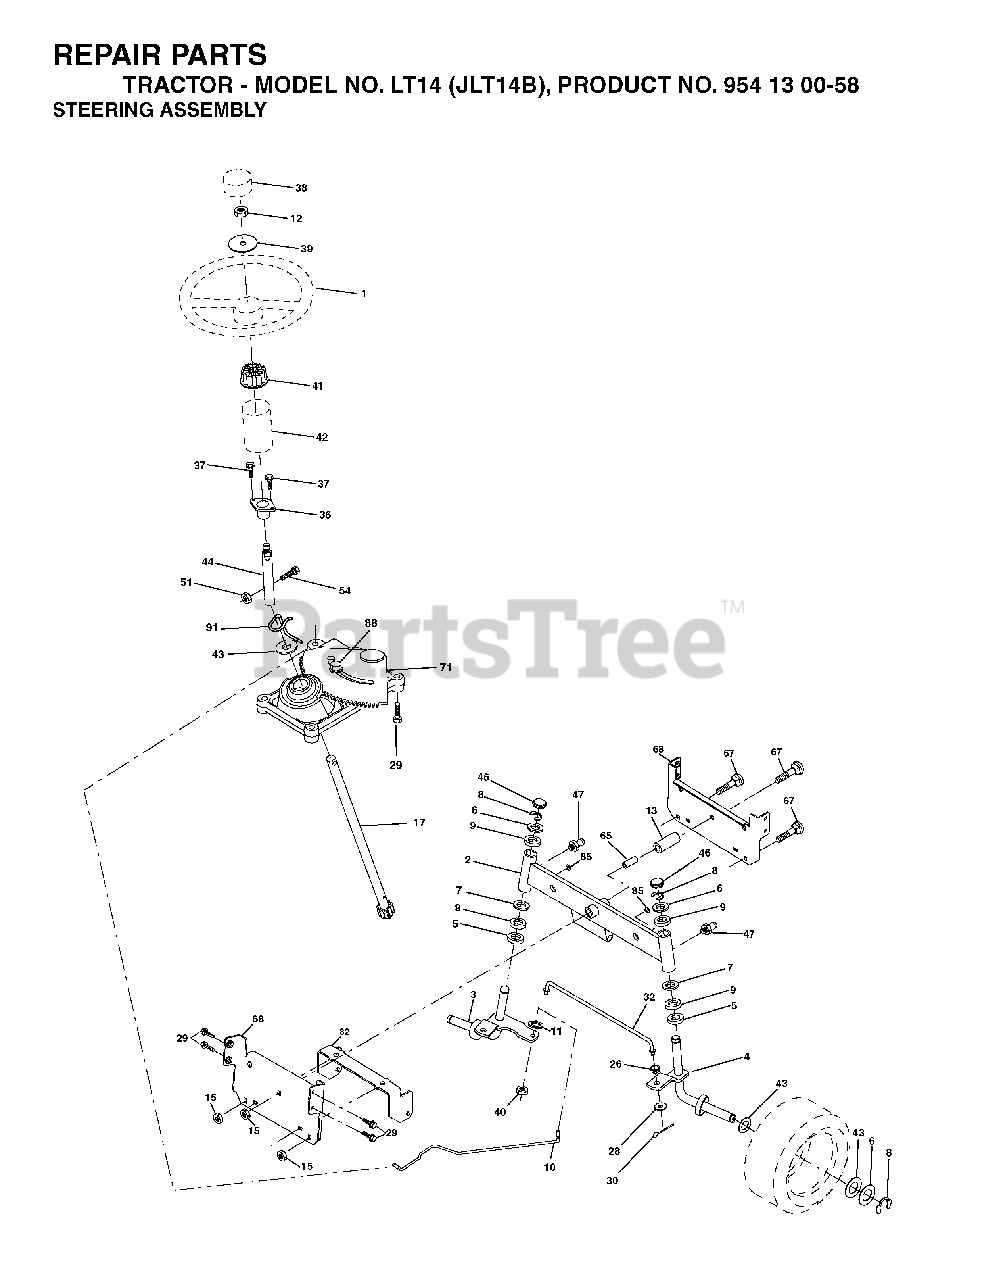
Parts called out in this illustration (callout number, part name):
2	AXLE ASM.
3	SPINDLE.ASM.LH.15"TIRES
4	SPINDLE.ASM.RH.15"TIRES
8	RING CLIP
9	BRNG T
10	DRAGLINK.15".TIRES.2001
11	WASHER, LOCK 3/8
12	NUT.HEX.1/2-20
13	TUBE, PIVOT AXLE
15	NUT
17	SHAFT ASM, STEERING
26	BUSHING.DRAGLINK
28	WASHER
29	SCREW 3/8-16X3/4
30	COTTER PIN
32	TIE ROD
36	BUSHING, STEERING
39	WASHER 9/16"ID, 2 3/8"OD
40	GRIPCO NUT
41	ADAPTER LT
42	BOOT.STEERING.SHAFT.BLACK
44	EXT, STEERING SHAFT
46	CAP.SPINDLE
47	FITTING.GREASE.TAPERED
51	CROWN LOCKNUT
65	SPACER BRACE AXLE
67	BOLT
68	BRACE.AXLE.15"TIRES
71	STEERING ASM
82	BRACKET
85	FASTENER.XMAS.TREE
88	BOLT, SHOULDER 7/16-20
91	CLIP.STEERING
